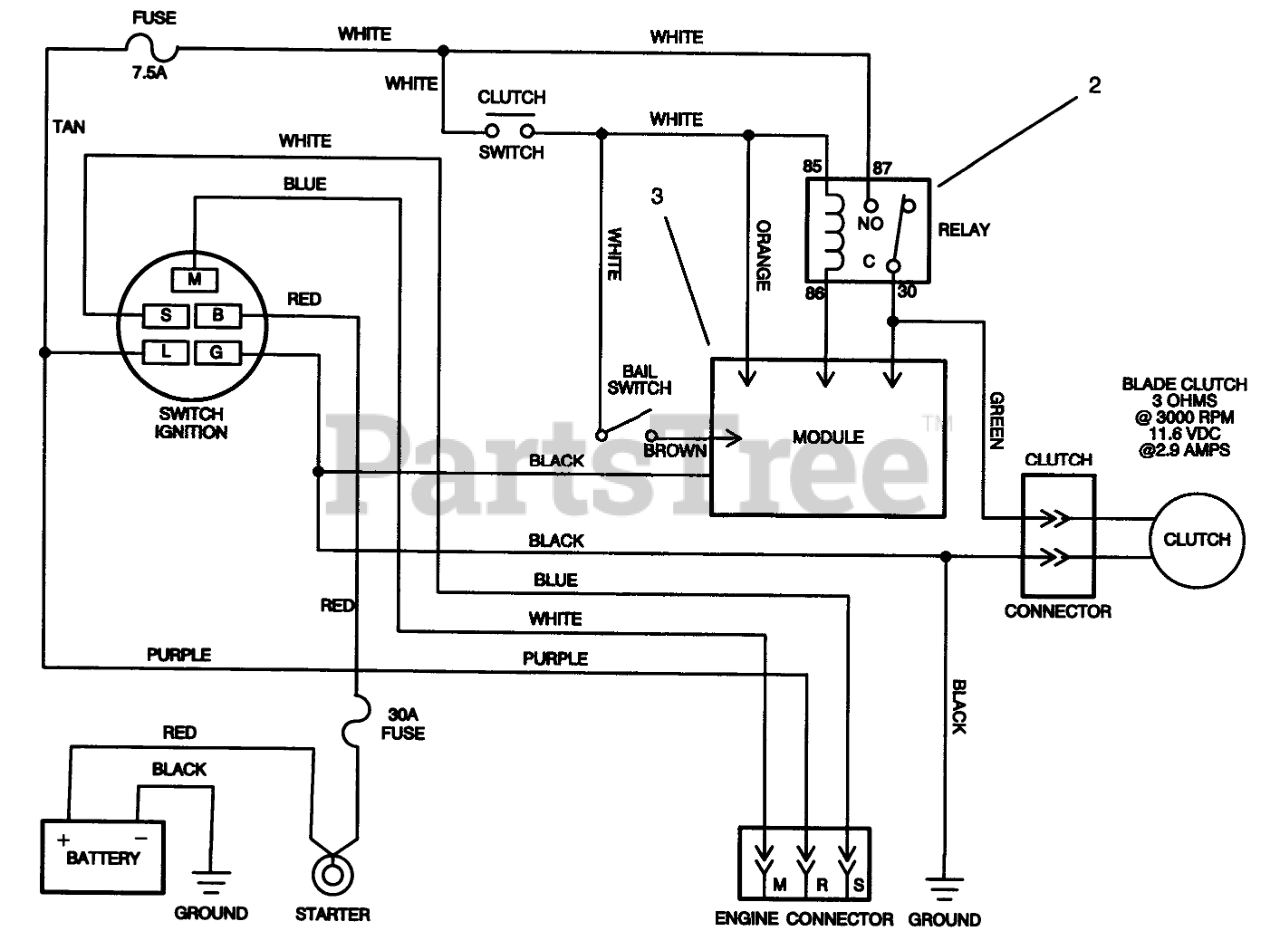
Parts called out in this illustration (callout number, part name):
1	WIRE HARNESS-18HP ELECT.
2	RELAY
3	Module
